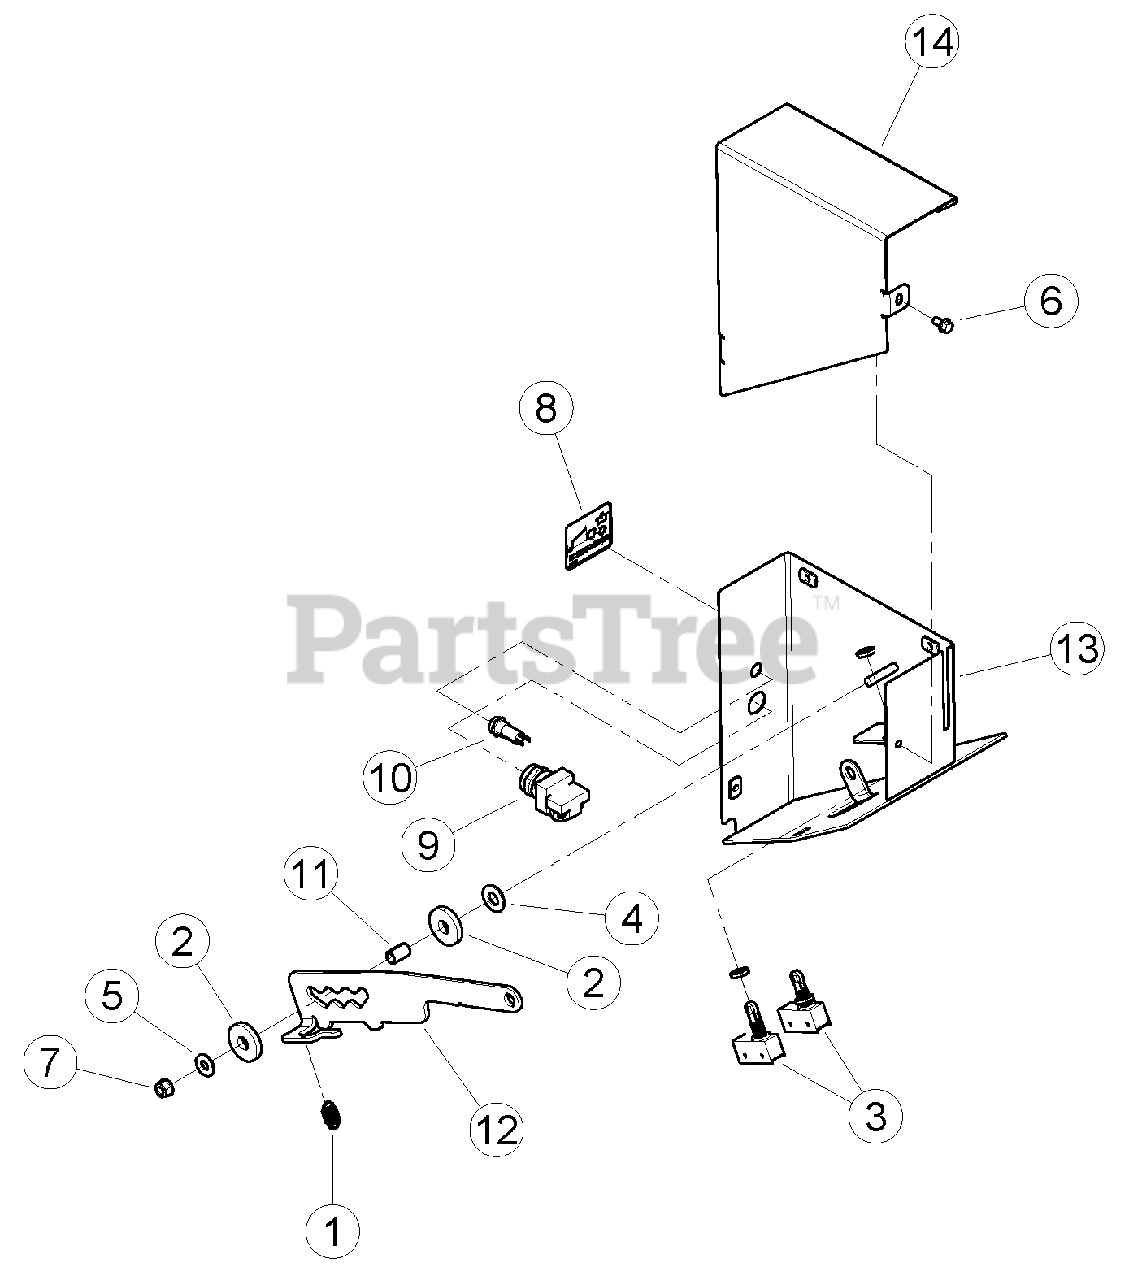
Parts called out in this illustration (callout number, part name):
1	SPRING, CONTROL BAR
2	WASHER, UHMW SPACER .515ID-1.50OD
3	SWITCH, FEED CONTROL
4	WASHER, 1/2 SAE FLAT ZP
5	WASHER, 5/16 FLAT ZP
6	BOLT, 1/4 X 1/2 SERR FLANGE GR5 ZP
7	NUT, 5/16-18 NYLOCK-FLANGE
8	DECAL, RESET/OVERRIDE
9	SWITCH, MOMENTARY IP65 NORMALLY OFF
10	LED, TRI-COLOR 12V 3-TERMINAL BASE
11	SPACER, .50 X .775
12	BAR, SWITCH CONTROL
13	WELDMENT, SWITCH BOX
14	PLATE, SWITCH BOX
